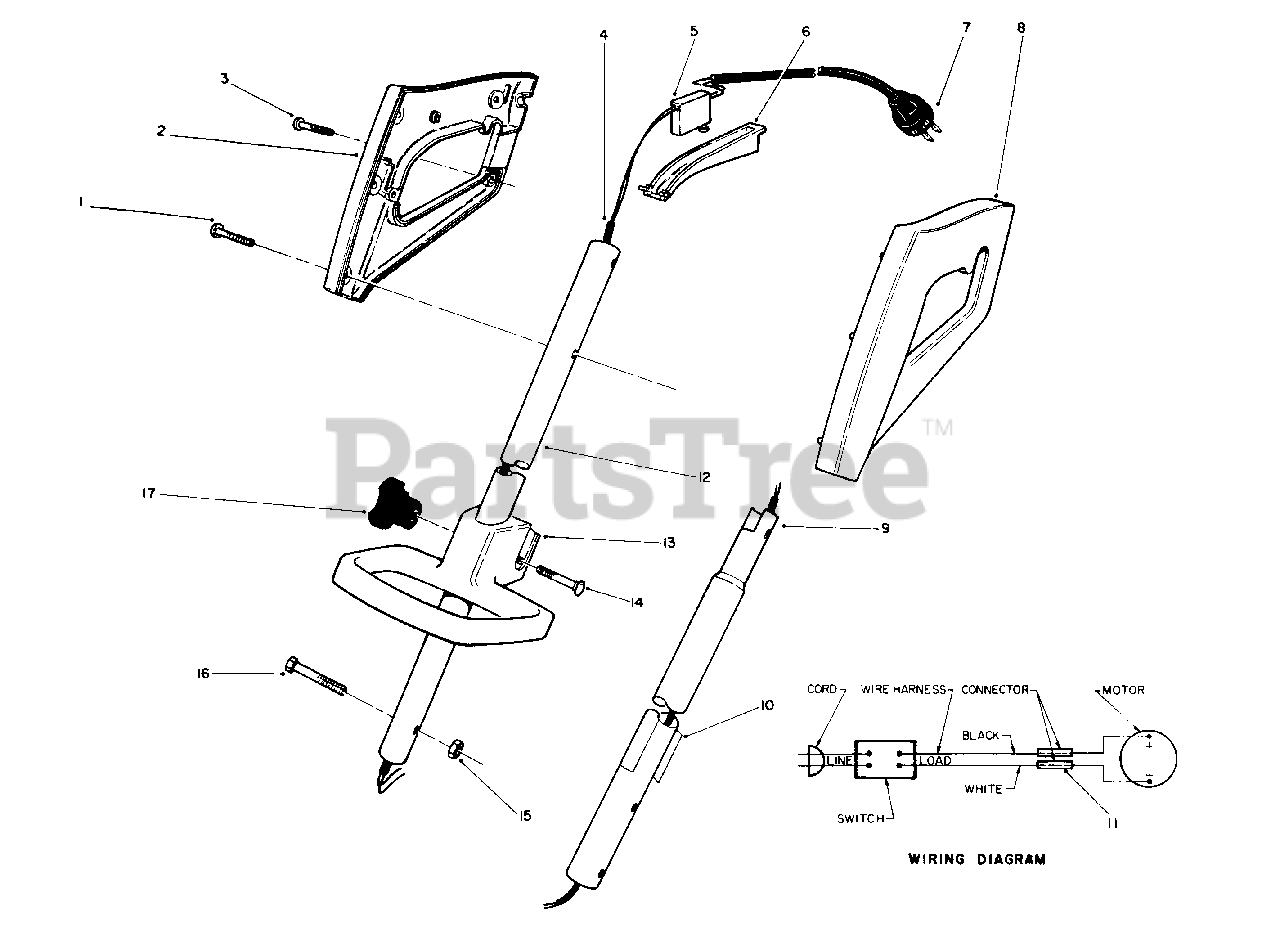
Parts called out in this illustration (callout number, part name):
1	Screw-Cap Hex. Hd.
2	Grip-Hand (R.H.)
3	Screw-Pan Hd.
4	Wire Harness Assembly
5	Switch
6	Bar-Switch
7	Cord-Power
8	Grip-Hand (L. H .)
9	Tube-Lower
10	Decal-UL
11	Connector
12	Tube-Upper
13	Handle Assembly
14	Bolt-Carriage
15	Nut-Lock
16	Screw-Cap Hex. Hd.
17	Knob-Adjustable Handle
